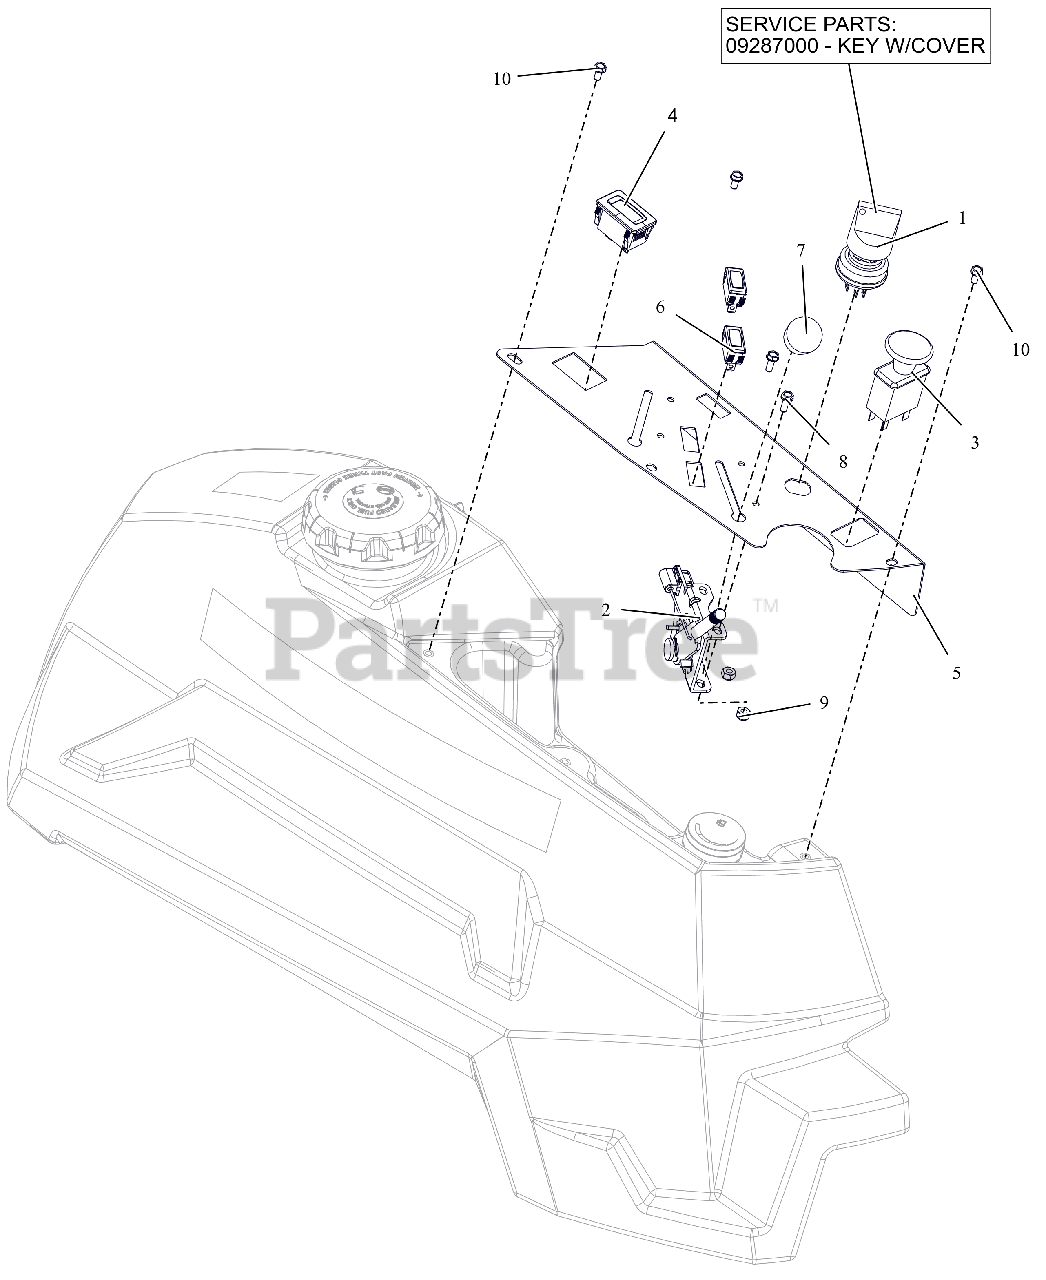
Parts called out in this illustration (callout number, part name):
1	SWITCH, IGNITION
1	KEY, W/ SHIELD
2	CABLE, PRO-CTRL 43.00"
3	SWITCH, CLUTCH
4	HOUR METER
5	PT400 CONTROL PANEL - RED
6	LIGHT, INDICATOR (RED)
7	KNOB-CONTROL-BLACK .38-16X.50
8	BLT, HWH #10-24X.50 ZCC
9	NUT-LK-NYL #10-24 G2 ZCC
10	SCR-MCH 10-24X.38 HWHSTAINLESS
